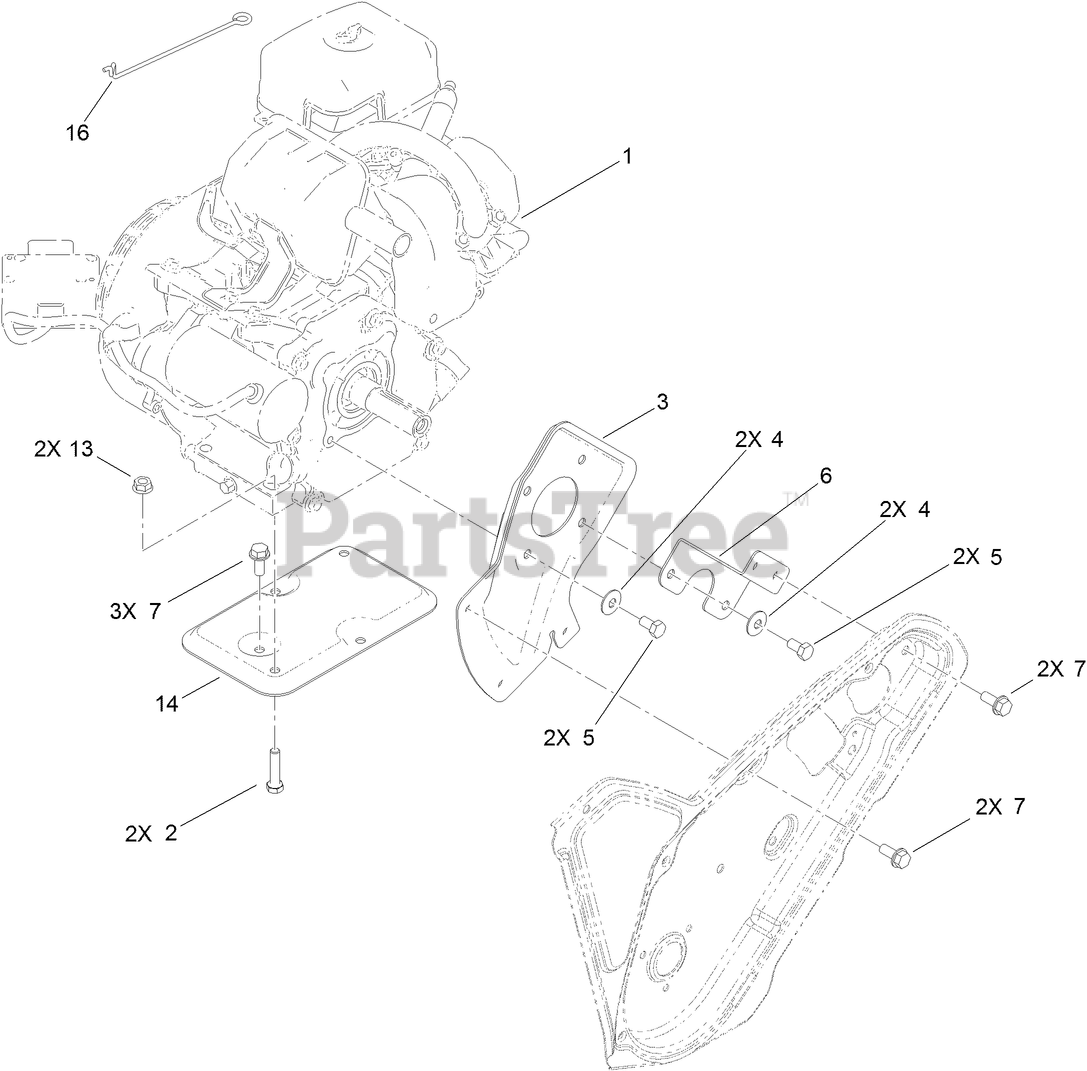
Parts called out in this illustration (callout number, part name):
1	ENGINE-168FDS-1
2	SCREW-HH
3	PLATE-ENGINE, PTO
4	WASHER-BELLEVILLE
5	SCREW-HH
6	SUPPORT-ENGINE, SIDE
7	SCREW-THD ROLL, HWH
13	NUT-HF
14	SUPPORT-ENGINE
